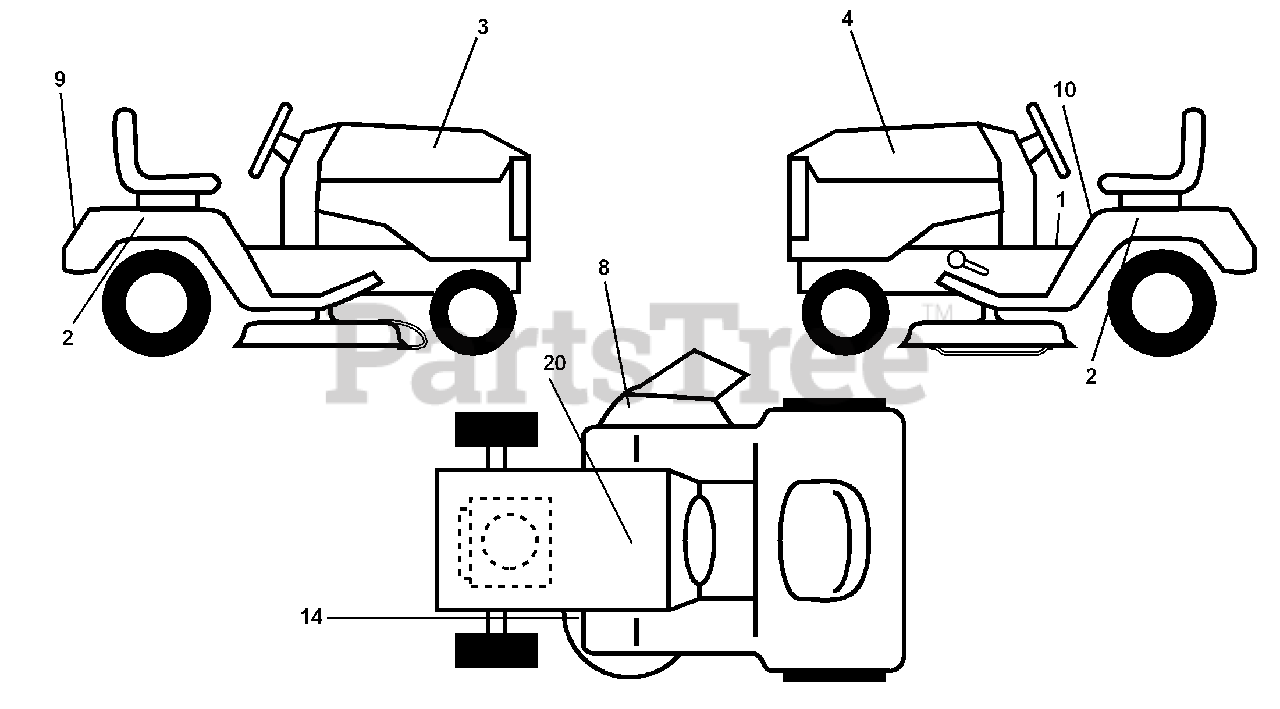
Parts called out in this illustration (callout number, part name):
1	Decal Oper Step Thru E/F
2	Decal Fender Auto Husq. Radius
3	Decal Hood RH
4	Decal Hood LH
8	Decal Warning
9	Decal Fender Husq
10	Decal Fender Danger E/F
14	Decal V-Belt Schematic
20	Decal Bat Dan/Psn
20	Decal Drawbar Cntrl Mvt Hyd Lt
20	Pad Footrest LH STLT
20	Pad Footrest RH STLT
20	Decal Handle Lft Height Adjust
20	Manual Owner's
20	42" Snow Blower
20	Wheel Wts
20	Grass Catcher
20	48" Snow Blade
20	Tire Chains
